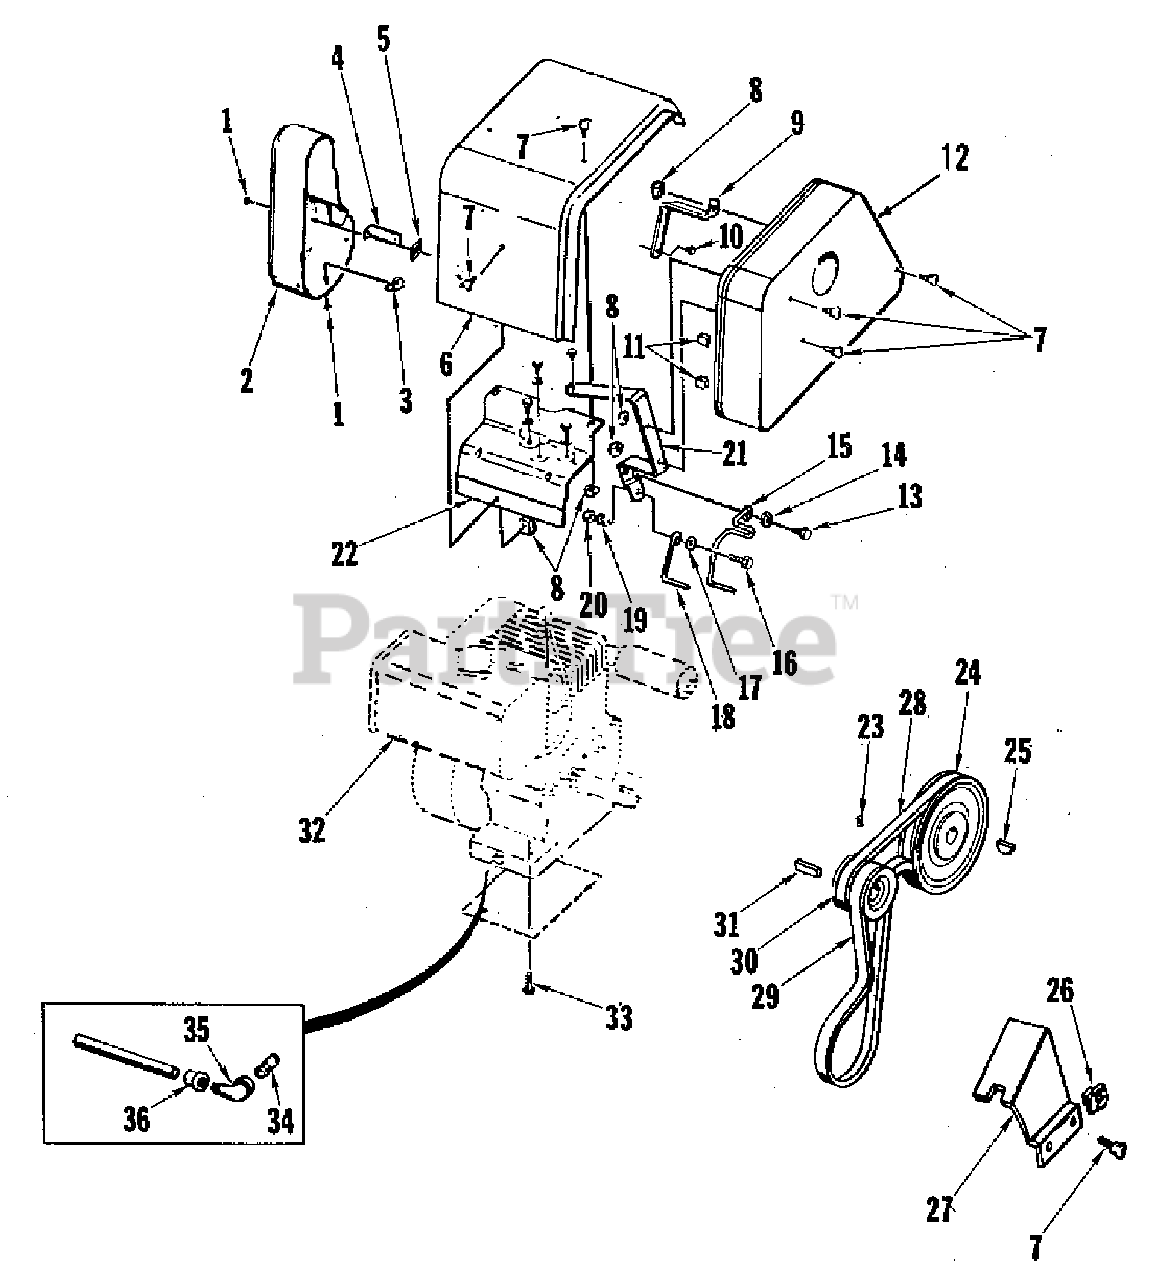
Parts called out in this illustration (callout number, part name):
1	SCREW, Self Tapping, #10-24 x 1/2" Lg.
2	SHIELD, Air Intake
3	NUT, Special, Tinnerman Speed
4	BRACKET, Air Intake Shield
5	NUT, Tinnerman
6	HOOD ASSEMBLY
7	SCREW, Thumb, 5/16-18 x 3/4
8	NUT, Tinnerman
9	BRACKET, Belt Guard
10	SCREW, Hex Head, Self Tapping, 1/4-20 x 3/8
12	GUARD ASSEMBLY, Belt
13	SCREW, Hex Head, 1/2-20 x 1
14	WASHER, Lock, 1/2" Internal
16	SCREW, Hex Head, 5/16-18 x 1
17	WASHER, Plain, 5/16"
19	WASHER, Lock, 5/16"
20	NUT, Hex, 5/16-18
21	SUPPORT, Belt Guard
22	BRACKET, Hood Support
23	SCREW, Set, 5/16-18 x 3/8
25	KEY, Woodruff
26	RETAINER, Nut
33	SCREW, 3/8-16 X 1
34	NIPPLE, Pipe
35	ELBOW, Street, 90 Degrees
36	PIPE, Cap, 1/4 Standard
